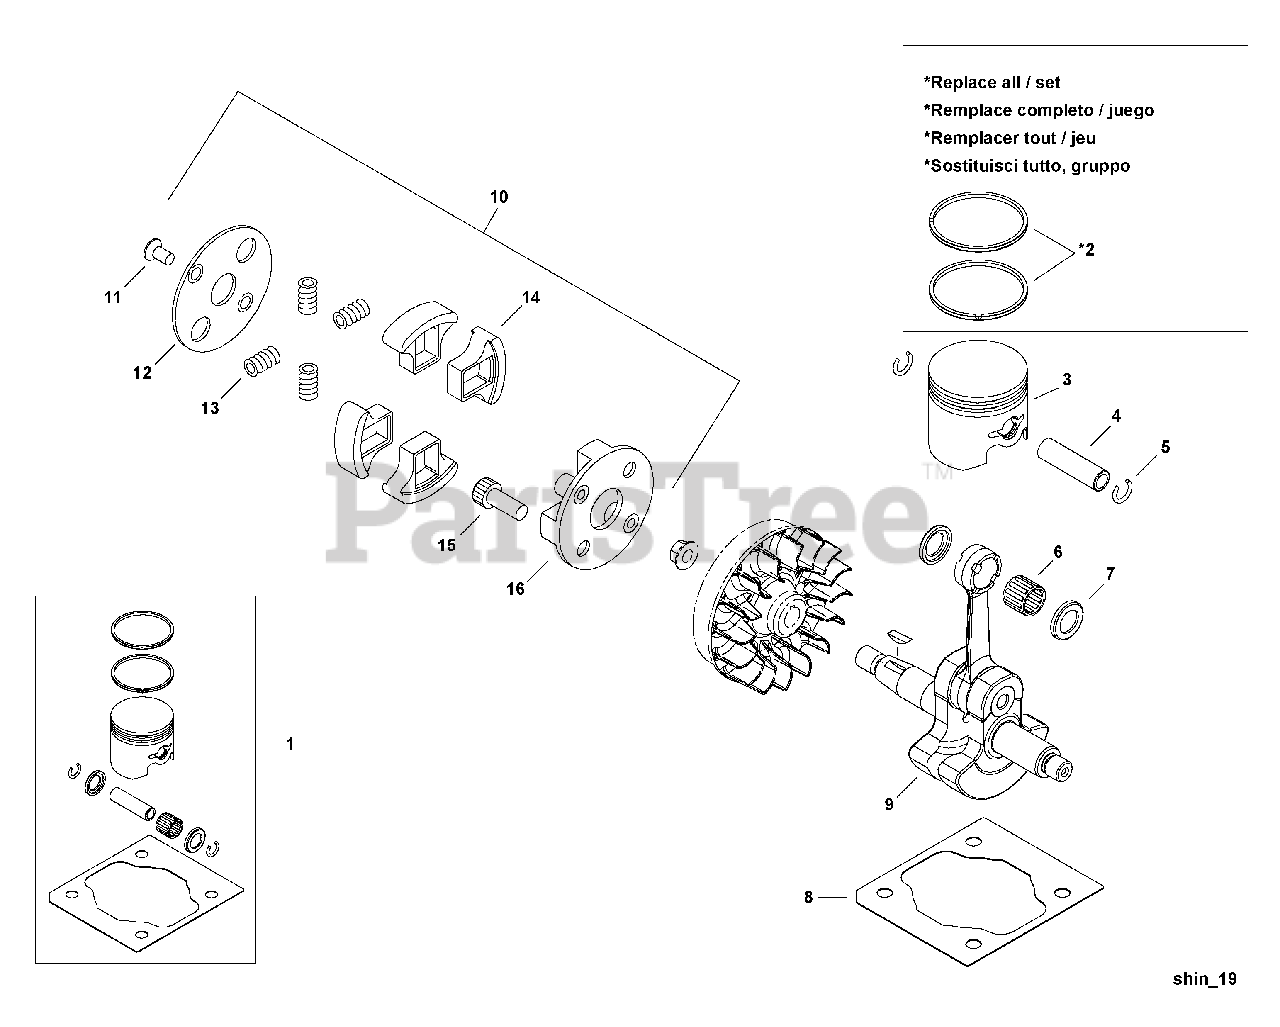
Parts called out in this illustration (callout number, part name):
1	PISTON KIT
2	RING, PISTON
3	PISTON
4	PIN, PISTON
5	RING, SNAP
6	BEARING, NEEDLE 9
7	WASHER, THRUST 9
8	GASKET, CYLINDER
9	CRANKSHAFT
10	CLUTCH ASSY
12	PLATE, CLUTCH
13	SPRING, CLUTCH
14	SHOE, CLUTCH
15	BOLT, CLUTCH
16	BOSS, CLUTCH
